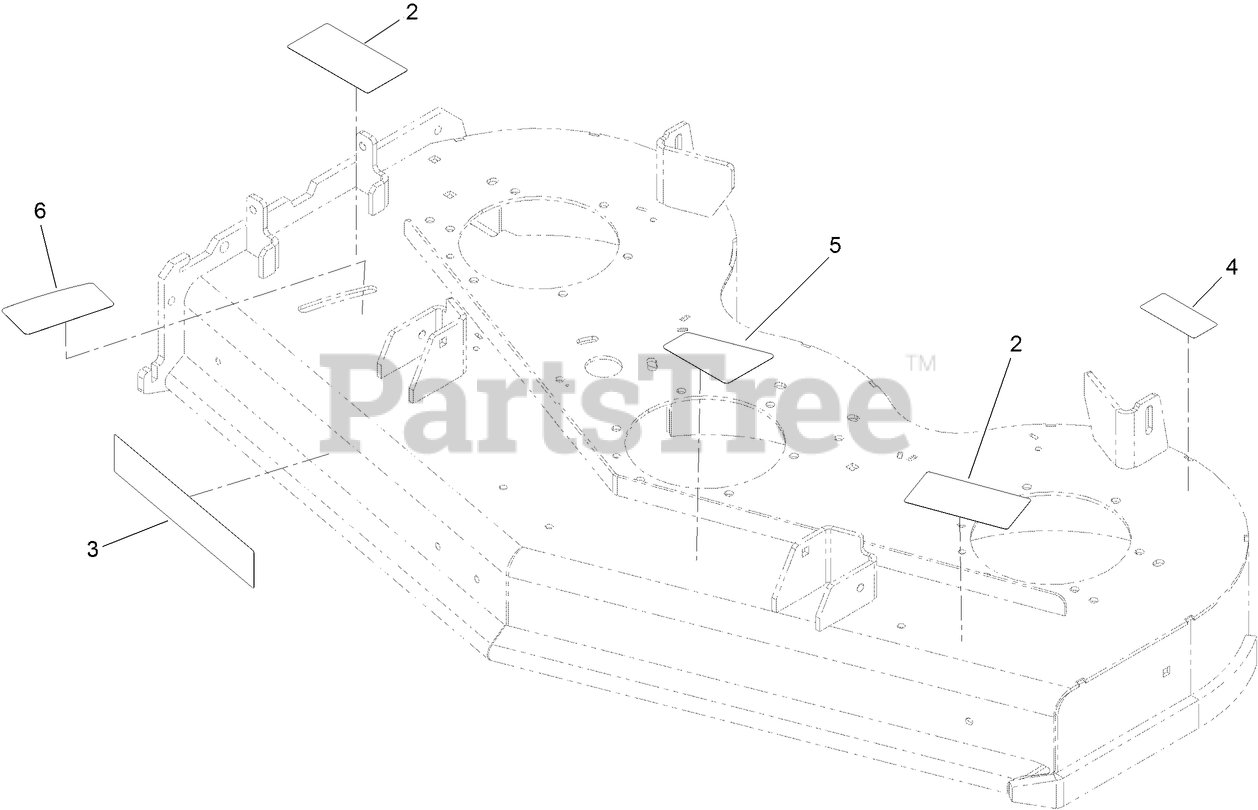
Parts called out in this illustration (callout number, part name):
2	DECAL-DANGER
4	DECAL-BOLT TORQUE
5	DECAL-BELT, TENSION (CE)
6	DECAL-ADJUSTMENT, BAFFLE
